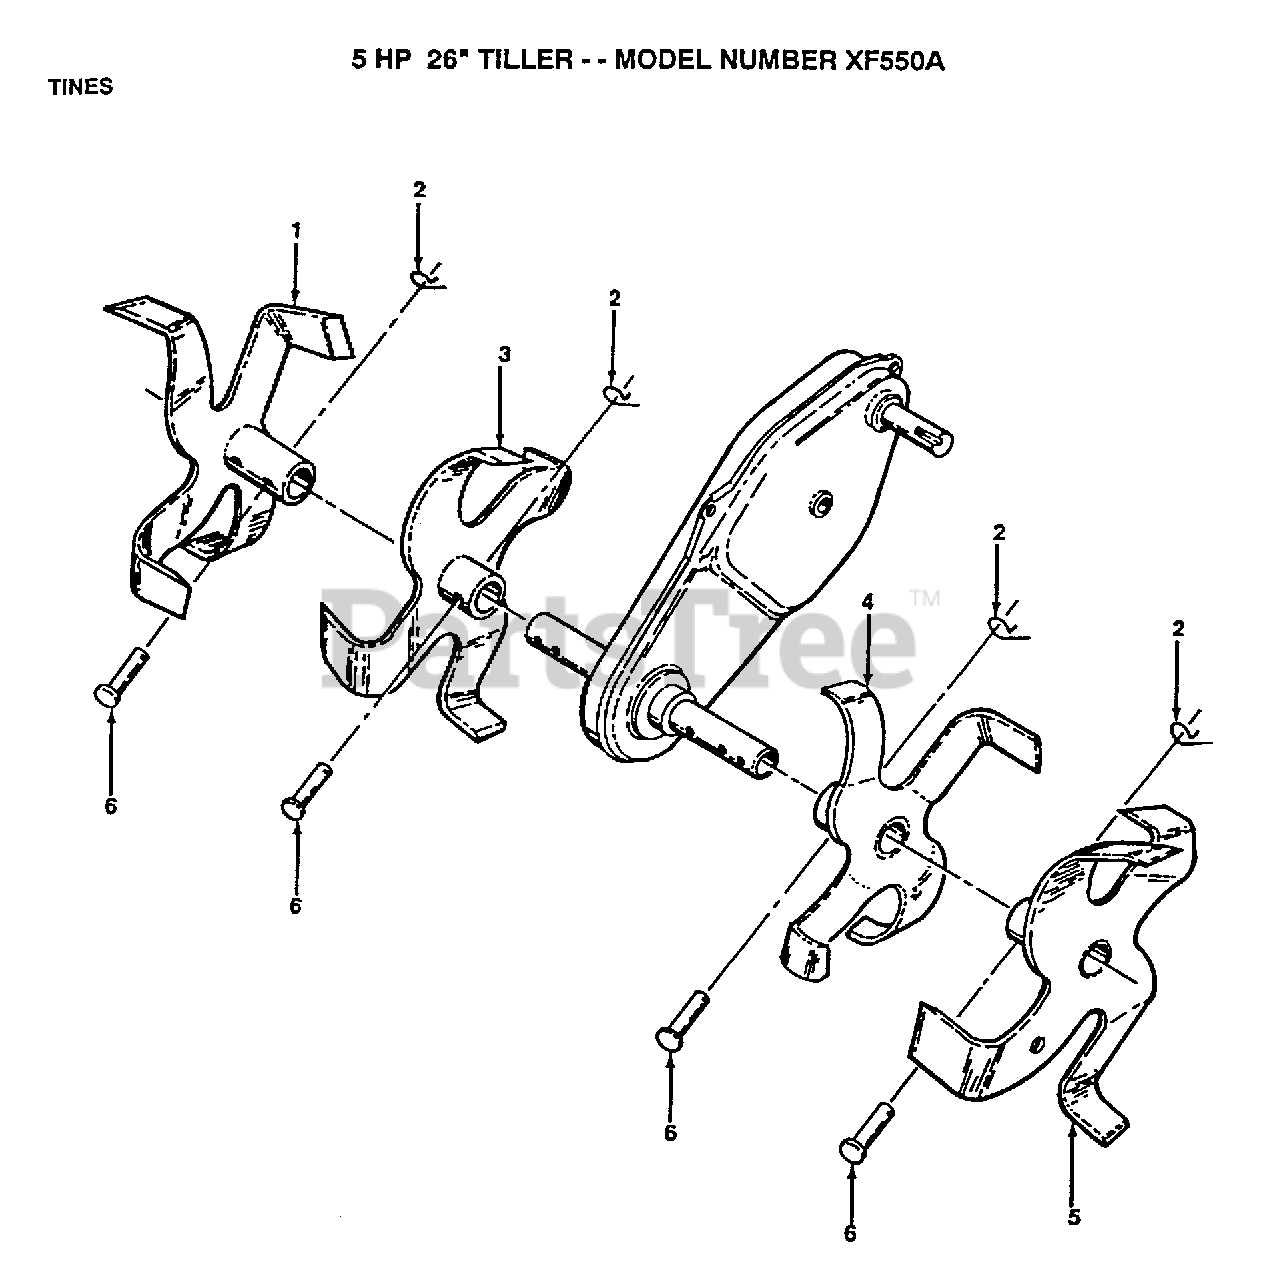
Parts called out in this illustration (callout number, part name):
1	TINE WELDMENT TI
2	RETAINER.SPRING
3	TINE TI
4	TINE TI
5	TINE WELDMENT TI
6	RIVET.PAN HD.1.75
